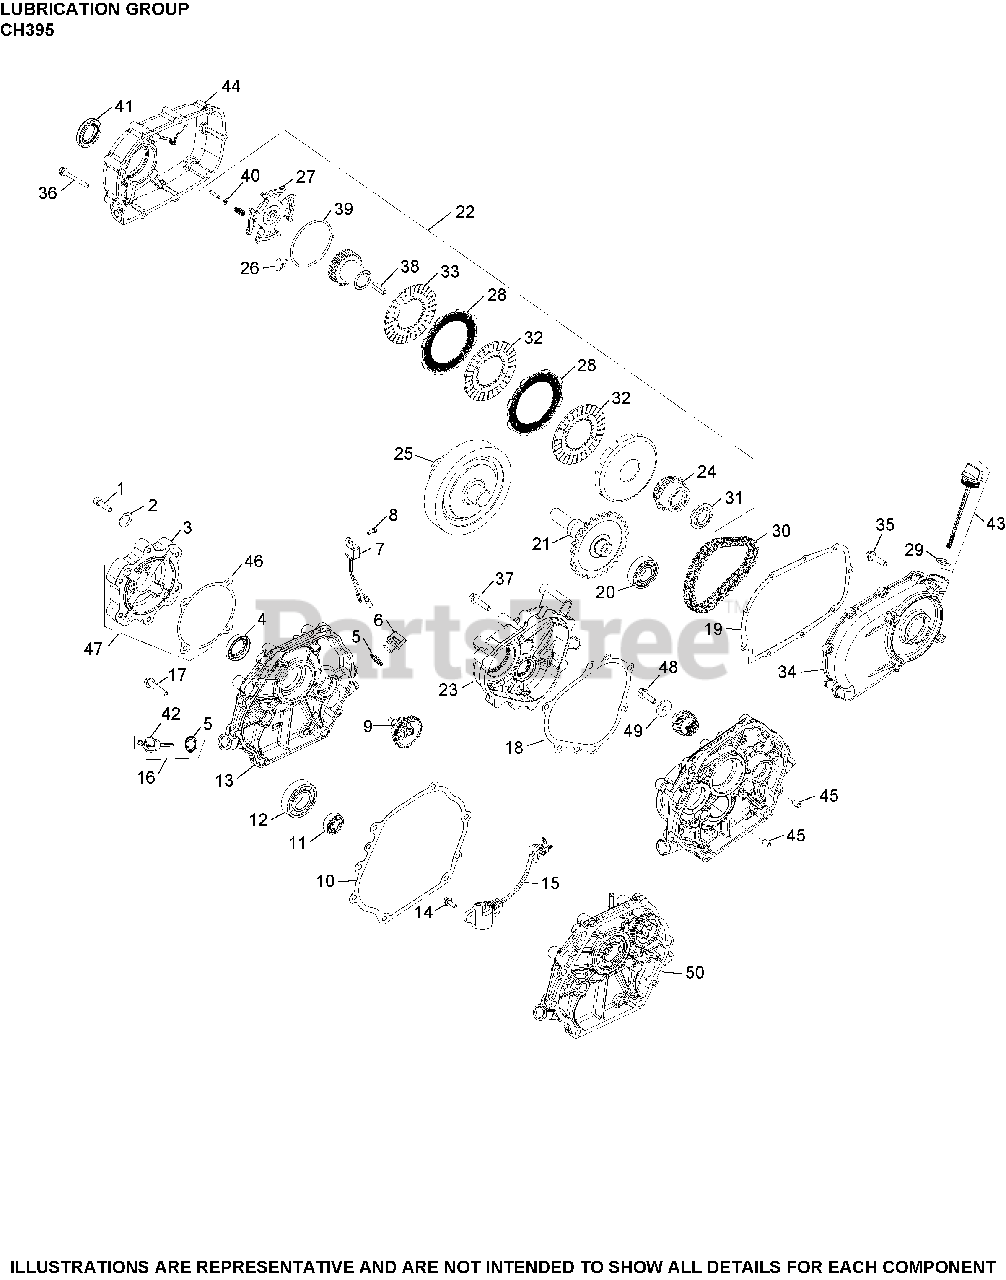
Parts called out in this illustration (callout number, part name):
1	SCREW, 5/16-24 X 1" UNF HSHC
2	WASHER, KNURLED SPRING LOCK
5	SEAL, OIL
7	CONTROL, OIL ALERT UNIT
8	SCREW, HEX/PHILLIPS M5
9	GOVERNOR, ASSEMBLY
12	BEARING, CRANKSHAFT
16	DIPSTICK ASSEMBLY
17	SCREW, CLOSURE PLATE (CKY)
42	DIPSTICK - USE 17 038 08-S
46	GASKET FLANGE, PTO ADAPTER
47	KIT, FLANGE, PTO ADAPTER
50	PLATE, CLOSURE & BEARING
